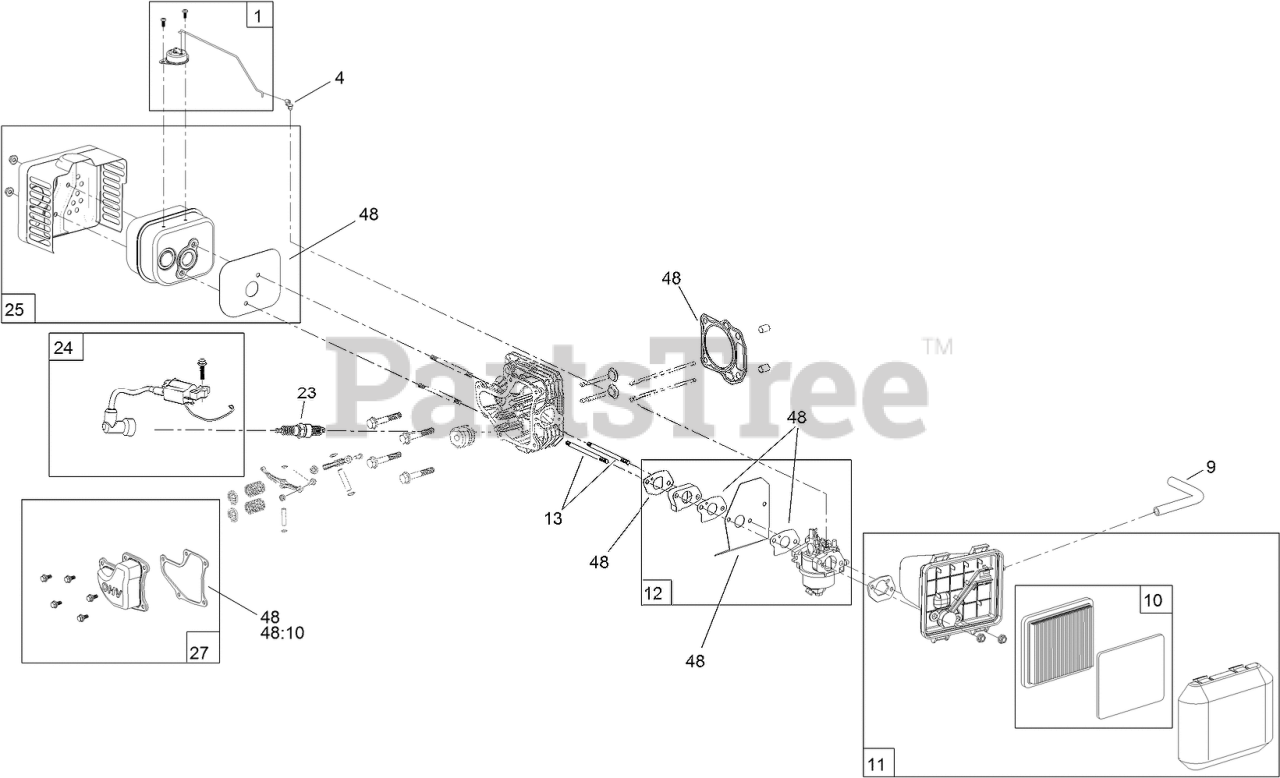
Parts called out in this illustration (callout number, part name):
1	THERMAL CONTROL KIT
4	LOCK-THROTTLE
9	TUBE-BREATHER
10	AIR FILTER AND PREFILTER KIT
11	AIR CLEANER ASM KIT
12	CARBURETOR REPAIR KIT
12	CARBURETOR COMPLETE KIT
13	STUD-INTAKE
23	SPARK PLUG
24	IGNITION KIT
25	MUFFLER AND SHIELD KIT
27	VALVE COVER KIT
48	SEAL AND GASKET KIT
48:10	GASKET-VALVE COVER
